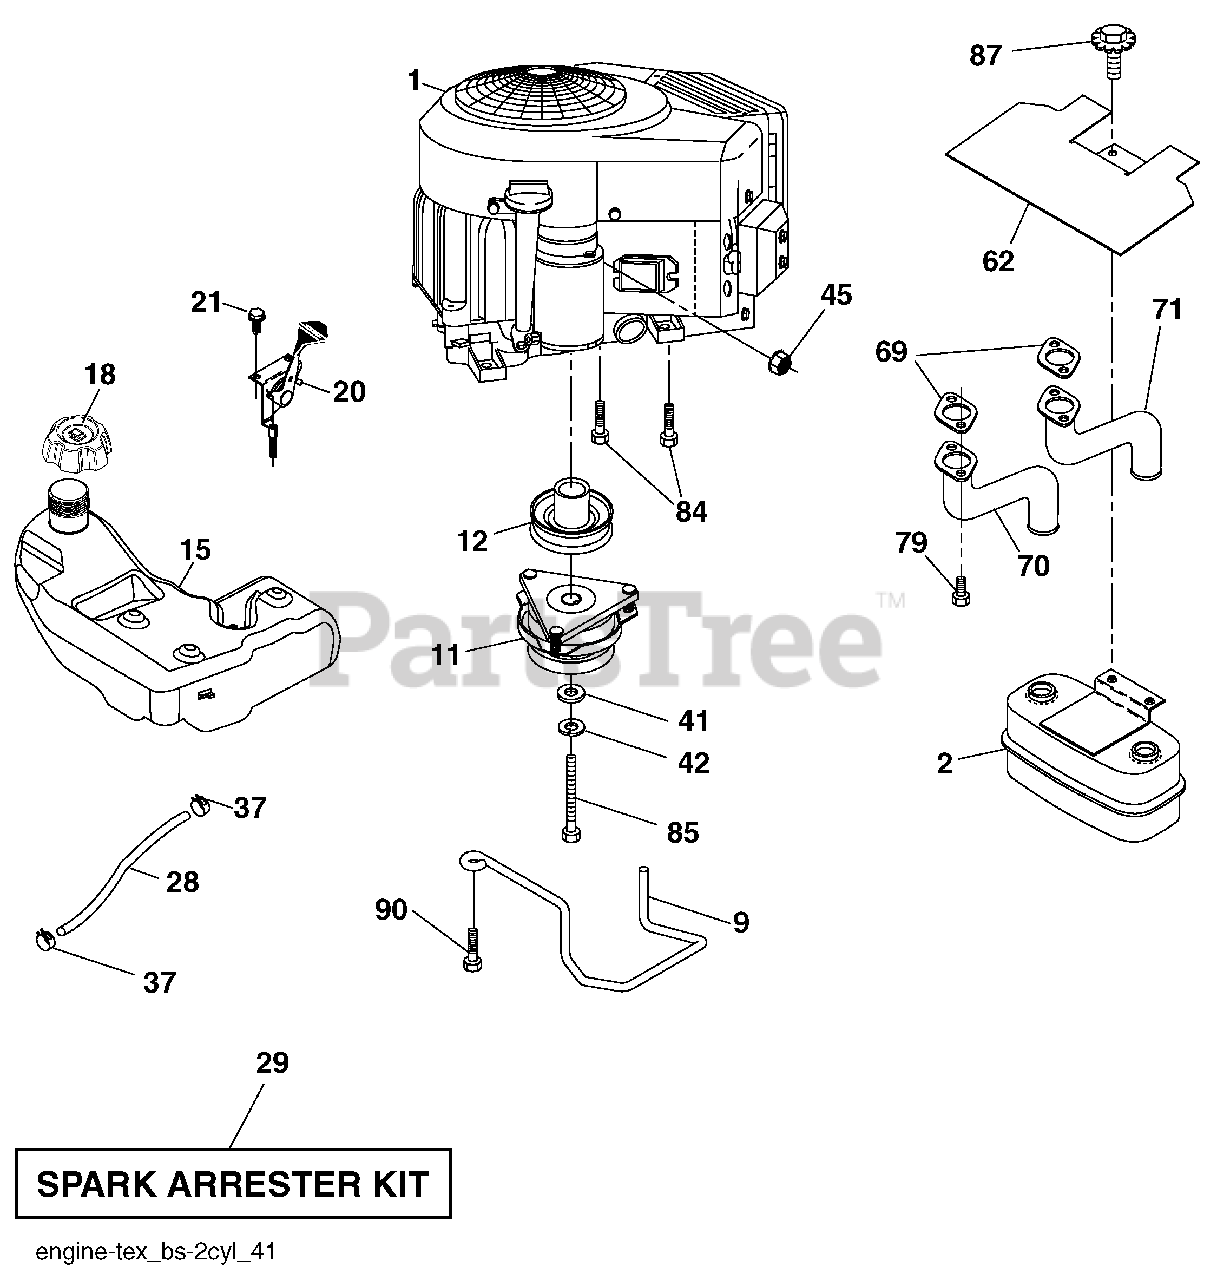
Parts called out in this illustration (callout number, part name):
2	Muffler
9	Keeper Belt Engine
11	Clutch Electric
12	Pulley Engine
15	Tank Fuel
18	Cap Fuel
20	Control Throttle/Choke
21	Screw #10 x 0.750 BOS Thread
28	Fuel Line
29	Spark Arrester Kit
37	Clamp Hose
41	Washer 1-1/2 OD x 15/32 ID x 250
42	Washer Lock 7/16
45	Nut Keps Hex 1/4-20 unc
62	Shield Heat Muffler
69	Gasket
70	Exhaust Tube LH
71	Exhaust Tube RH
79	Screw Socket HD 5/16-18 x 1
84	Screw 3/8-16 x 1-1/4
85	Bolt 7/16-20 x 4 x Gr. 5-1.5
87	Bolt 5/16 - 18 x 3/4
90	Screw 3/8-16 x 1
